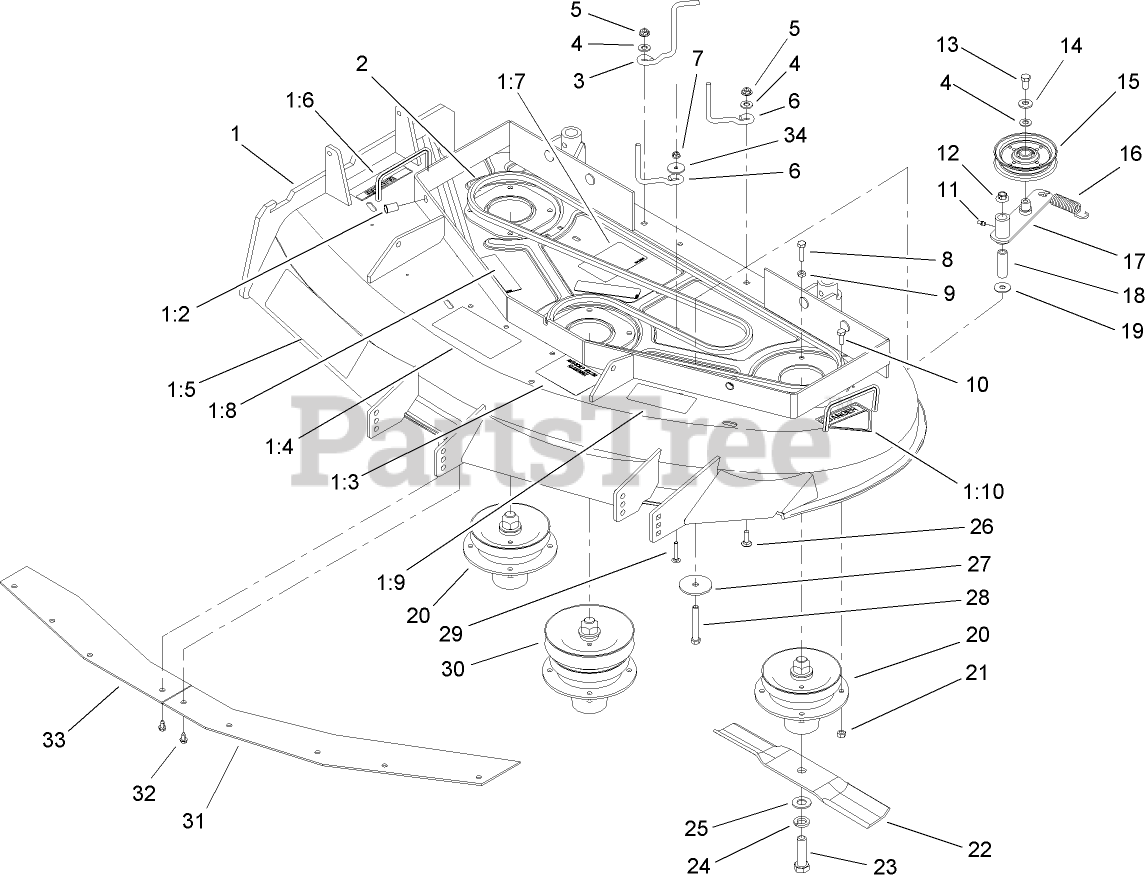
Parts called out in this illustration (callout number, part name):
1	DECK ASM
1:2	INSERT-NUT
1:3	DECAL-ANTI SCALP
1:4	DECAL-DANGER, THROWN OBJECT
1:6	DECAL-DANGER
1:7	DECAL-ROUTING, BELT
1:8	DECAL-DANGER
1:9	DECAL-TORQUE
1:10	DECAL-DANGER
2	V-BELT
3	Guide-Belt
4	WASHER-FLAT
5	NUT-HF
6	ROD-BELT
7	NUT-LOCK, HHF
8	SCREW-HH
9	NUT-JAM
10	SCREW-HH
11	FITTING-GREASE
12	NUT-HF
13	SCREW-HH
14	WASHER-BELLEVILLE
15	PULLEY-IDLER
16	Spring-Extension
17	IDLER ARM ASM
18	TUBE-IDLER
19	WASHER
20	Spindle Housing ASM
21	NUT-LOCK, CONE
23	SCREW-BLADE
24	WASHER-LOCK
25	WASHER-FLAT
26	BOLT-CARR
27	WASHER-END
28	SCREW-HH
29	SCREW-CARR
30	Spindle Housing ASM
31	PLATE-BLOWOUT, LH
32	SCREW
33	PLATE-BLOWOUT, RH
34	Washer-Retainer, Pulley
